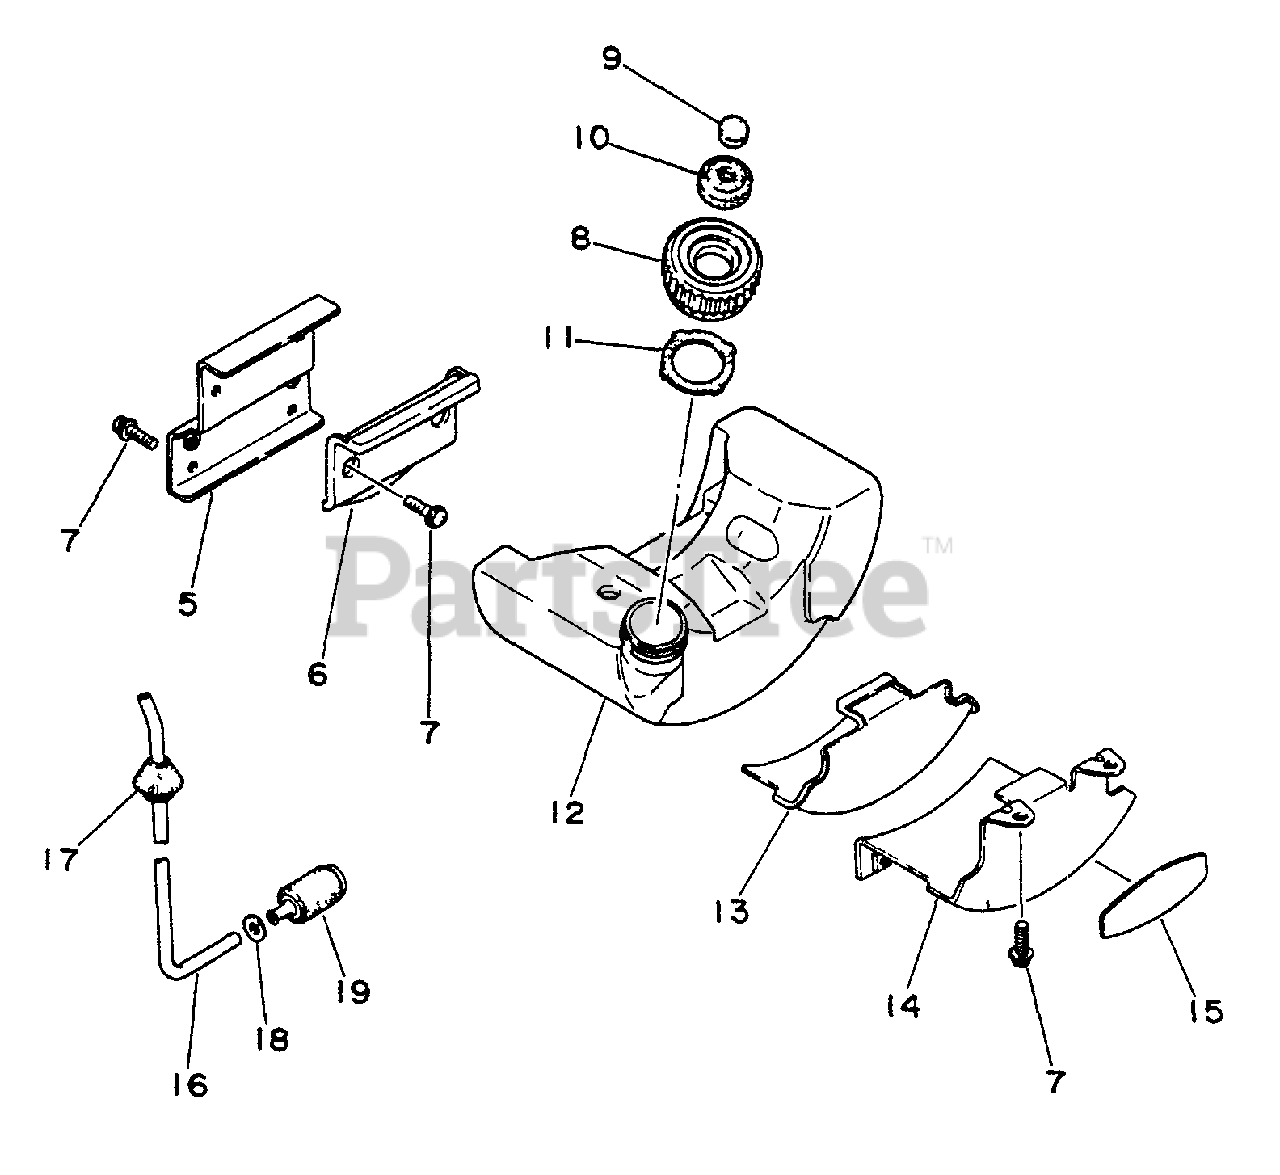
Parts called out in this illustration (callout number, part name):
5	BRACKET, FUEL TANK
6	CUSHION, FUEL TANK
7	SCREW - 4X14
8	CAP ASSY
11	GASKET, CAP
12	TANK, FUEL
14	BRACKET, FUEL TANK
15	LABEL - ECHO
16	PIPE - 3X6X135 -- BLACK
18	WASHER - 5
19	FILTER, FUEL
